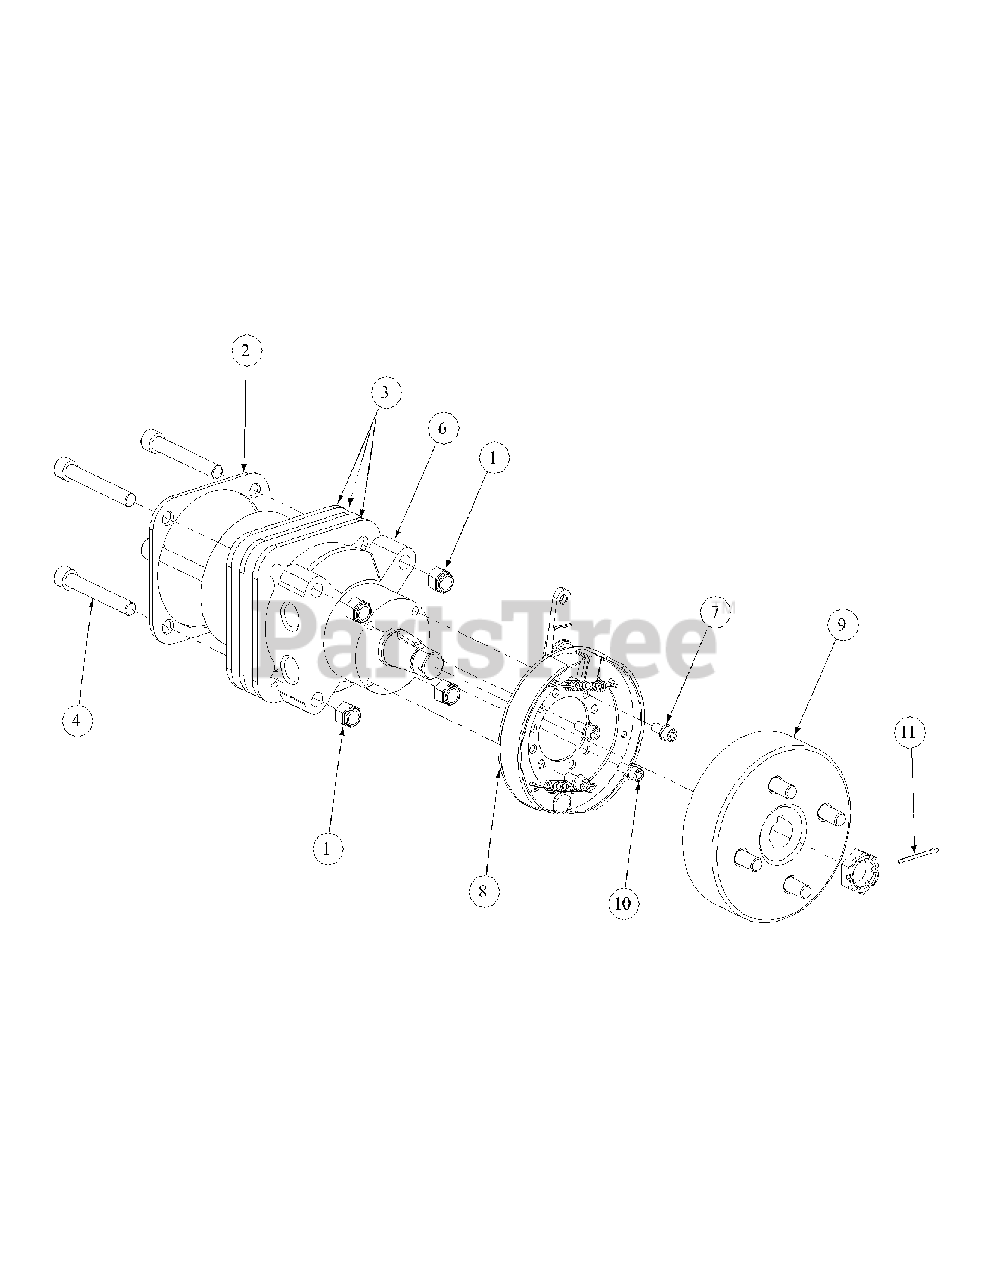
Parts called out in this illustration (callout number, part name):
1	Lock Nut, Nylon Insert, 1/2-13
2	Motor Plate
3	Motor Spacer
4	Socket Head Capscrew, 1/2-13; 3-1/2
4	Capscrew, 1/2-13 x 3.5
5	Hyd. Motor, Parker Left Hand
6	Hyd. Motor, Parker Right Hand
7	Lock Washer, 5/16
8	Brake Assembly w/Line
9	Hub and Drum Assembly w/Studs
10	Capscrew w/Socket, 5/16-18 x 3/4
11	Cotter Pin 1/8 x 1-1/2
